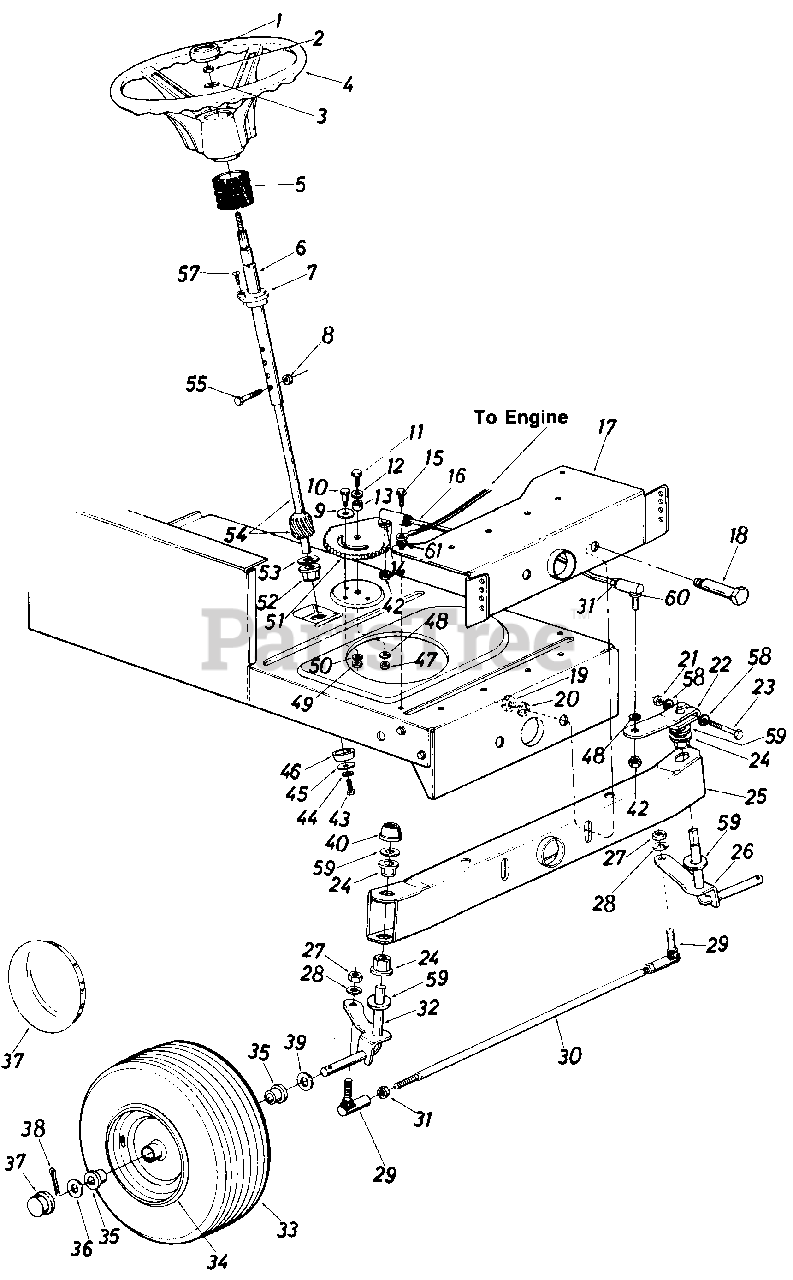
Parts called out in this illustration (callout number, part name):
1	Steering Wheel Cap
2	Hex L-Nut 5/16-24 Thd.
3	Belleville Wash. .345" I.D.
4	Steering Wheel
5	Steering Bellow-4.5"
6	Steering Column Ass'y.
7	Flange Bearing .890 I.D. x 1.36 O.D.
8	Hex L-Nut 1/4-20 Thd.
9	Fl-Wash. .438" I.D. x 1.37" O.D.
10	Shoulder Bolt .437" Dia. x .35 Lg. 5/16-18 Thd.
11	Hex Bolt 3/8-24 x 1.0" Lg. (Grade 5)
12	Bell-Wash. .4" I.D. x 1.13" O.D.
13	Spacer .380" I.D. x .625" O.D. x .227
14	L-Wash..38" I.D.*
15	Hex Wash. Hd. Self-Tap Scr.
16	Steering Drag Link
17	Front Pivot Brkt.
18	Shoulder Bolt .498" Dia. x 2.04 Lg. 3/8-16 Thd.
19	Hex Nut 3/8-16 Thd.
20	L-Wash. 3/8" I.D.*
21	Hex Cent. L-Nut 5/16-24 Thd.
22	Steering Arm Front Axle
23	Hex Bolt 5/16-24 x 2.00" Lg. (Grade 5)
24	Hex Flg. Brg. .634 I.D.
26	Front Axle Ass'y.-L. H .
27	Hex Nut 3/8-24 Thd.
28	L-Wash. 3/8" I.D.*
29	Ball Joint 3/8-24 Thd.
30	Tie Rod
31	Hex Jam Nut 3/8-24 Thd.
32	Front Axle Ass'y.-R.H.
33	Wheel Ass'y. Comp.
34	Front Wheel Rim Only
35	Bearing
36	Fl-Wash. .635 I.D. x 1.59 O.D.
37	Front Wheel Hub Cap
38	Cotter Pin 118" Dia. x 1.25"*
39	Fl-Wash. .640" I.D. x 1.24" O.D.
40	Push Cap 518" Dia. Rod
42	Hex Nut 3/8-24 Thd.
43	Hex L-Bolt 5/16-18 x .62"
44	L-Wash. 5116" I.D.*
45	Fl-Wash. .344" I.D. x 1.25" O.D.
46	Spacer (Plastic)
47	Hex Nut 3/8-24 Thd.
48	L-Wash. 3/8" I.D.
49	Hex Nut 5/16-18 Thd.
50	L-Wash. 5/16" I.D.*
51	Steering Gear Segment
52	Hex Flg. Brg. .634 I.D.
53	Fl-Wash. (Hardened)
54	Steering Shaft Lower
55	Hex Bolt 1/4-20 x 1.25" Lg.
57	Oval Hd. Cr.-Sunk Scr. #10 x 5/8" Lg.
58	Wave-Wash. .32" I.D. x .62n O.D.
59	Fl-Wash. (Hardened)
60	Drag Link Ball Joint 3/8-24 Thd.
61	5/16" Ext. Lock Wash.
